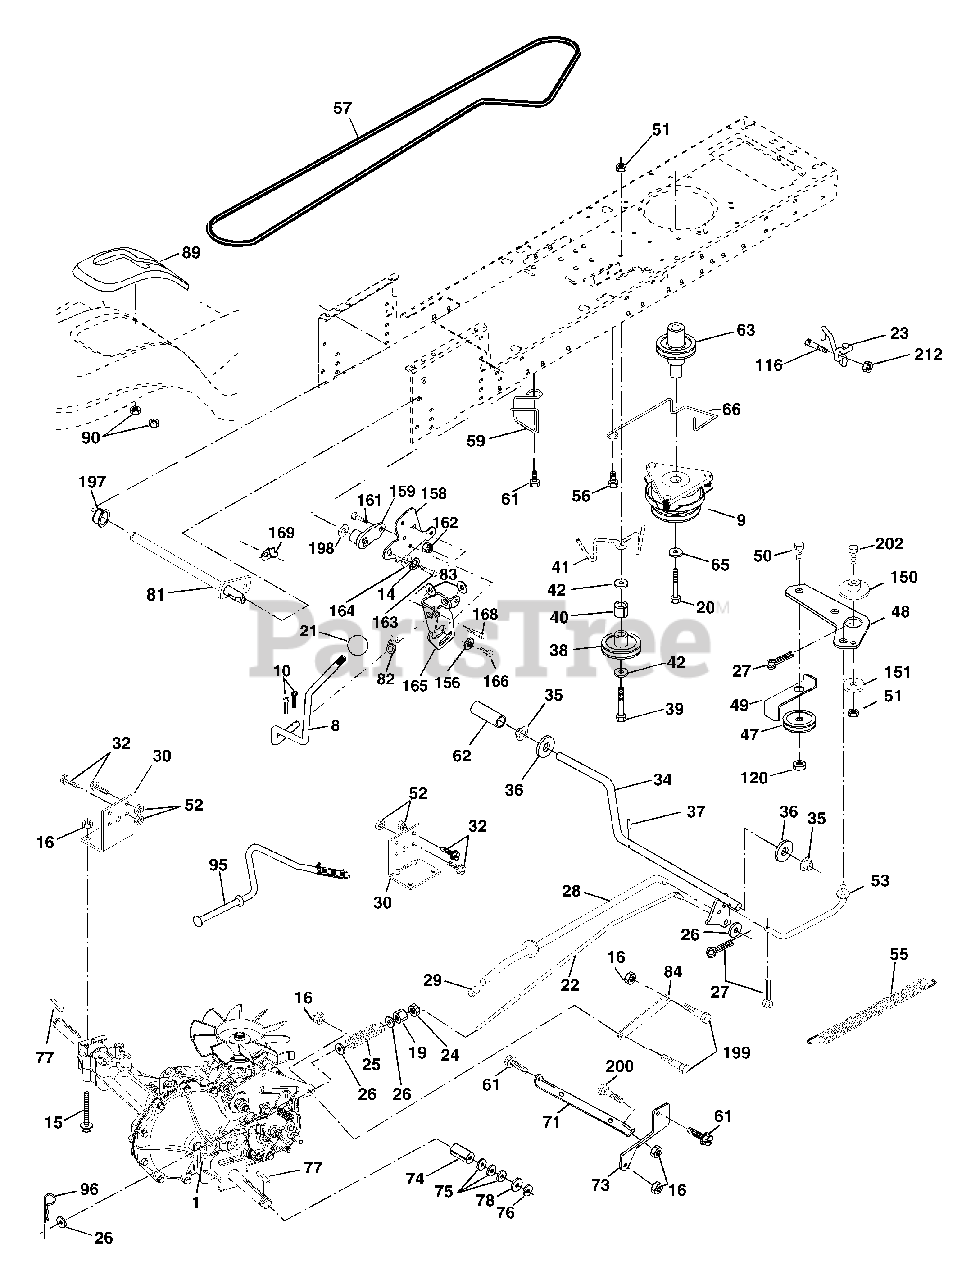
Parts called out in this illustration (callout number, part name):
1	Transaxle, Hydro
8	Rod Shift Fender Adjust STLT
9	Clutch Elecric
10	Pin Cotter 1/8 x 1 CAD
14	Washer Lock Hvy Helical
15	Bolt Hex 5/16-18 Unc Flghd
16	Nut Lock Hex W/Ins. 5/16-18 Unc P
19	Nut Lock Hex W/Ins 3/8-16 Unc
20	Bolt, Hex 7/16-20 x 4-1/4 Ga. 5
21	Knob Deluxe 1/2-13 UNC BLK/BLK
22	Rod, Brake Hydro
23	Bracket Asm Mtg CL
24	Nut Hex Jam 3/8-16 UNC
25	Spring, Brake Rod
26	Washer
27	Pin Cotter 1/8 x 3/4 CAD.
28	Rod, Parking Brake
29	Cap,Parking Brake
30	Bracket, Transaxle
32	Bolt Hex Hd 5/16-18 Unc x 3/4
34	Shaft, Foot Pedal
35	Bearing, Nylon
37	Pin, Roll
38	Pulley, Composite, Flat
39	Bolt, Fin, Hex 3/8-16 x 3
40	Spacer Split
41	Keeper, Belt Idler
42	Washer 13/32 x 13/16 x 12 Ga
47	Pulley, Idler, V-Groove Plastic
48	Bellcrank Clutch Grnd Drv STL
49	Retainer, Belt Style Spring
50	Bolt Hex Hd 3/8-16 Unc x 1-1/2
53	Link, Clutch
55	Spring, Return, Clutch
56	Screw 3/8-16 x 1.0
57	V-Belt, Ground Drive
59	Keeper, Center Span
61	Screw 3/8-16 x 3/4
62	Cover, Pedal
63	Pulley, Clutch Elect
65	Washer Lock Hvy HLCL Spr 7/16
66	Keeper Belt Engine
71	Strap Torque Lh Hydro
73	Strap Torque Rh Hydro
74	Spacer, Axle
75	Washer 25/32 x 1-1/4 x 16 Ga.
77	Key, Square
78	Washer 25/32 x 1-5/8 x 16
81	Shaft Asm Cross Tapered
82	Spring Torsion T/A
83	Washer 17/32 x 3/4 x 16 Ga.
84	Link Transaxle
89	Console, Shift
90	Nut Self Thd 1/4
95	Control Asm. Bypass Hydro
96	Retainer Spring 1" Zinc/Cad
116	Bolt Rdhd Sqnk 3/8-16 Unc x 1
120	Nut Lock Flg 3/8-16
150	Spacer Retainer
151	Washer 13/32 x 2 x 10 Ga.
156	Washer Srrted 5/16ID x 1.125
158	Bracket Shift Mount
159	Hub Tapered Flange Shift Lt
161	Bolt Rdhd Sqnk 1/4-20 x 3/4 Gr 5
162	Nut Crownlock 1/4-20 Unc
163	Bolt Hex Fin 1/4-20 Unc x 1 Gr 5
164	Washer 5/8 x .281 x 10 Ga
165	Bracket Pivot Lever
166	Screw 5/16-18 x 5/8
168	Bolt Shoulder 5/16-18 x .561
169	Plate Fastening STLT/CRD
197	Nyliner Snap 5/8" ID
198	Washer Nyl 7/8 ID x .105 Hyd
199	Bolt Shoulder 5/16-18 Unc
200	Bolt Rdhd Sqnk 5/16-18 Unc x 1
212	Nut Hex Flange Lock
